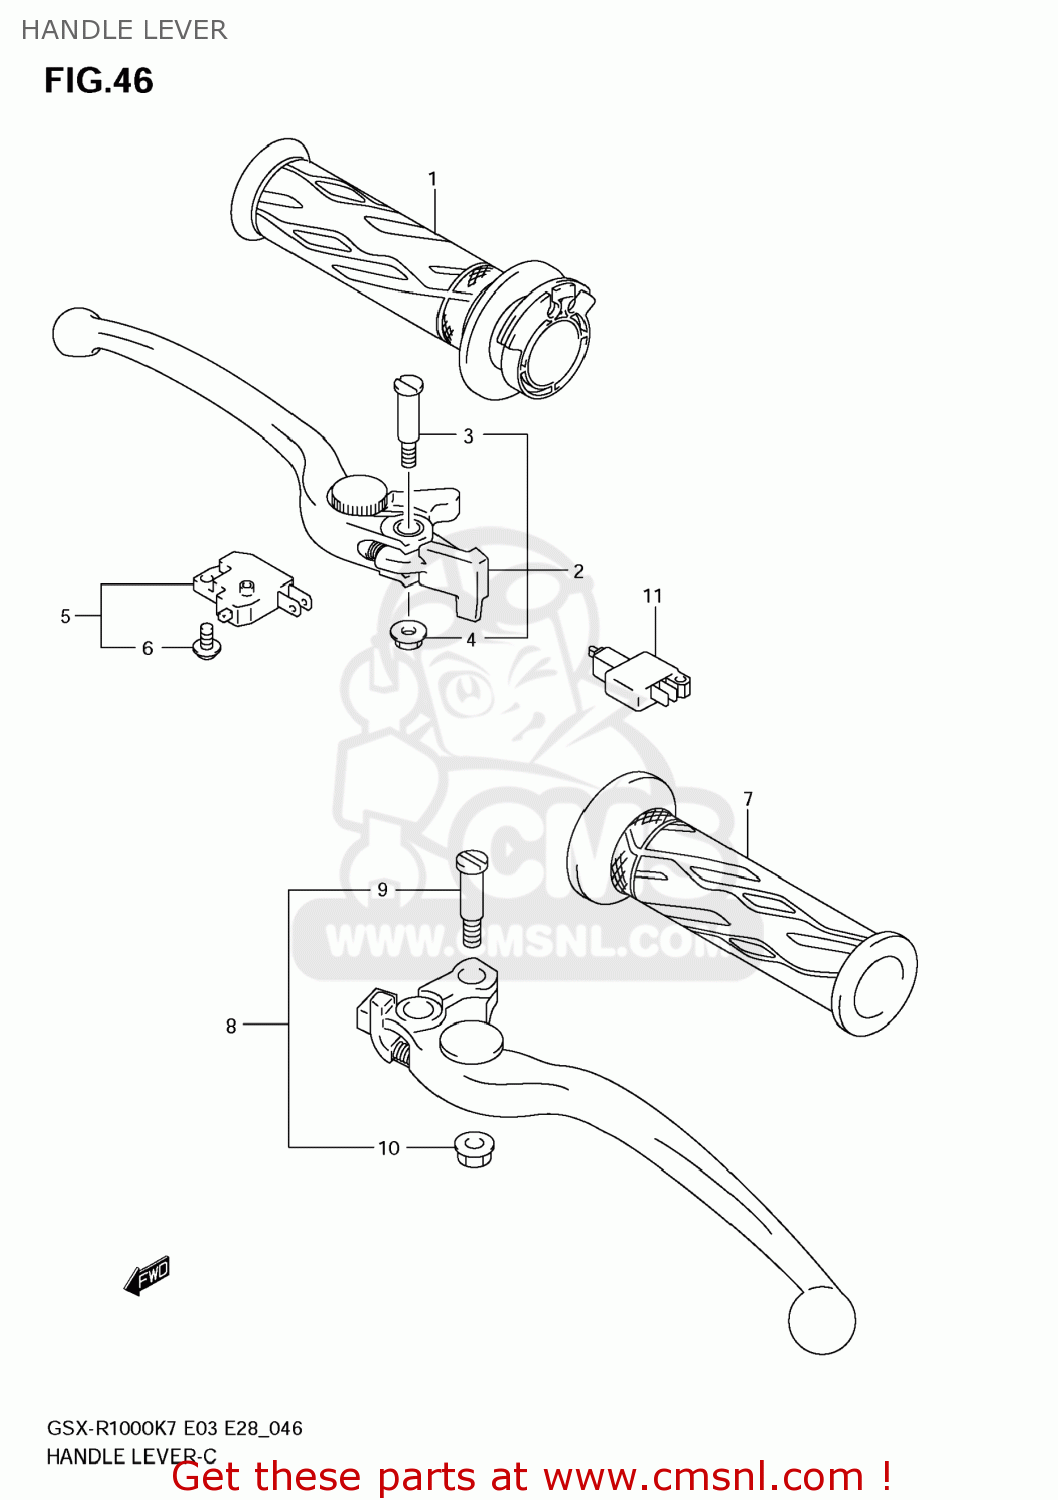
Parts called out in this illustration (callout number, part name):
1	GRIP COMP,THRO
2	LEVER ASSY,BRA
3	BOLT,LEVER PIVOT
4	NUT,LEVER PIVOT
5	SWITCH ASSY,ST
6	SCREW
7	GRIP,L
8	LEVER ASSEMBLY,CLUTCH
9	BOLT,LEVER PIVOT
10	NUT
11	SWITCH ASSY,CLUTCH
